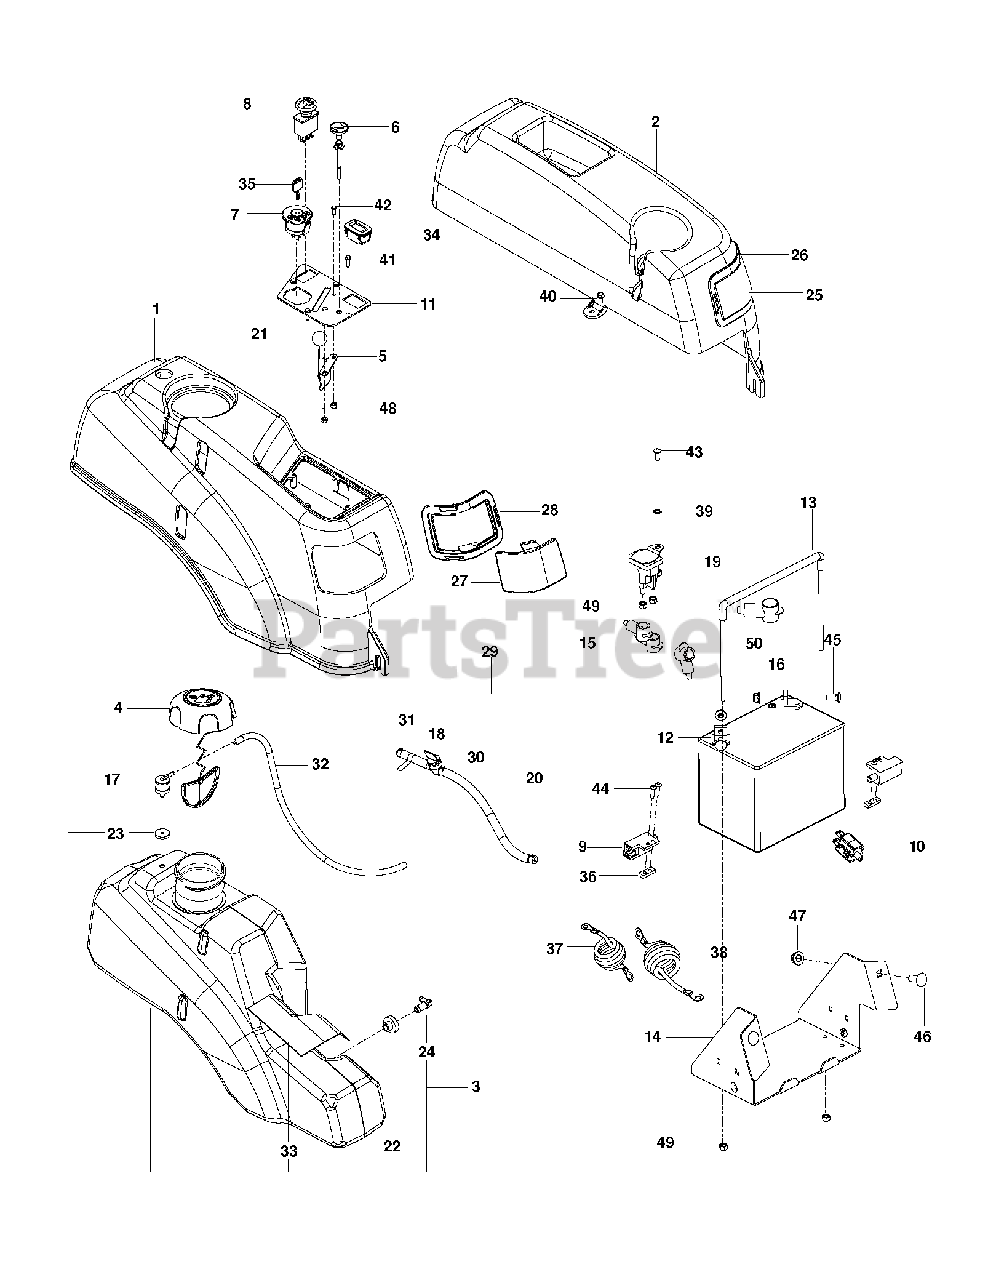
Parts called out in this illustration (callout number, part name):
1	FENDER.RT.BLK.3IN.FUEL.NECK
2	FENDER, LT, BLK
3	Fuel Tank Assembly, Large
4	Fuel Cap Assembly, 3" Black
5	THROTTLE CABLE
6	CHOKE CABLE
7	IGNITION SWITCH
8	PTO SWITCH
9	SWITCH INTERLOCKT
10	SWITCH.INTRLCK.CLUTCH.
11	CONTROL PLATE RZ STD X431
12	BATTERY, 12 V 300 AMP
13	BATTERY TIE DOWN ASSEMBLY
14	BOX, BATTERY, BLACK
15	COVER.TERMINAL.RED
16	INSULATOR
17	VALVE.FUEL.CHECK
18	FUEL VALVE
19	SOLENOID.W/BRASS.PLUNG
20	HOSE CLAMP
21	KNOB ROUND BALL
22	RUBBER GROMMET
23	GROMMET, CHECK VALVE
24	STEM, FUEL TANK
25	PANEL, LT
26	RING, LT BLK
27	PANEL, RT, BLK
28	RING, TRIM, RT-BLK
29	Fuel Hose Shut-off Assembly, 10" 3"
30	HOSE.1/4".LOW.PERM.FUEL.LN.10"
31	HOSE.1/4".LOW.PERM.FUEL.LN.3"
32	HOSE.3/16".VAPOR.LINE.18"LGTH
33	SHIELD, HEAT
34	Hour Meter Gauge
35	KEY MLD GEN DELTA
36	PLATE NUT ZTR
37	BATTERY CABLE, NEGATIVE
38	CABLE POSITIVE, LONG
39	WASHER 1/4 INT TOOTH
40	HCS 1/4-20.
41	SCR #10-12X3/4 HEX WAS HD ZD
42	HCS #10-24 X 1/2
43	SCR 1/4-20 X 5/8 BTN SKT HD ZD
44	SCR #10-24 X .75 SKT HD BLK
45	BOLT
46	BOLT D
47	NUT 3/8-16 HEX FLG NYLOC ZD
48	NUT 10-24 NYLOC
49	LOCKNUT
50	5/16-18 NYLOC FLANGE NUT
